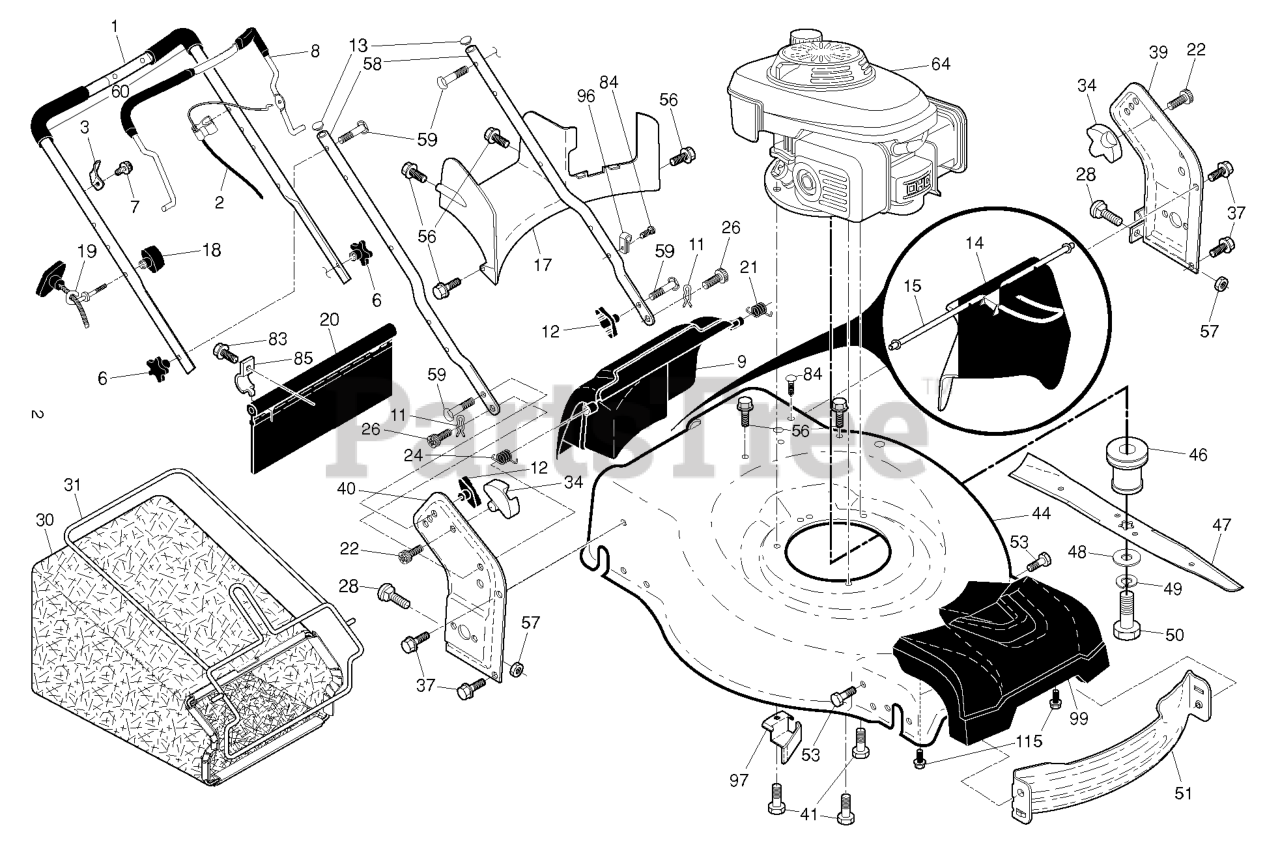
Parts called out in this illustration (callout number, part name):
1	HANDLE.UPPER.3.POS.BS.AW2.GREY
1	HANDLE.ASM.UPPER.W/GRIP
2	CABLE.MZR.50.SNAP-IN
3	BRACKET.UPSTOP.RT
6	KNOB.HANDLE.PLASTIC.STAR.BLACK
8	BAIL.OVER.MOLD.ERGO.MZR.ORANGE
9	DOOR.REAR.ASM.22+.HUSQ.FG/RGD
11	COTTER.HAIRPIN.DOOR/HANDLE.PIV
12	KNOB, DEFLECTOR
13	PLUG.PLASTIC.7/8".14-20.GAUGE
14	DEFLECTOR.CHUTE.22+REAR
15	HANDLE DEFLECTOR.22+REAR
17	BAFFLE.REAR.22+RGD.AWD.PLASTIC
18	T-KNOB.NEW ROPE GUIDE
19	GUIDE.ROPE.BLK.ZINC.CHROM
20	SKIRT.REAR.22+RGD.HIGH WHEEL
20	SKIRT.REAR.22PLUS.RGD.LW(2 2MC
21	SPRING.LH.BLACK
22	SCREW.PAN.HEAD.#10
24	SPRING.RH.GRAY
26	BOLT.CARRIAGE.LN.5/16-18X.5/8
26	SCREW,DOOR/HANDLE.PIVOT
28	BOLT
30	GBAG.A361029ER.HUSQ.GRY/SIL
31	FRAME.GBAG.22+.BLK
34	BRACKET.GRASSBAG.ATTACHING.BLK
37	BOLT.5/16HEX.WHS.HD
39	BRACKET.ASM.HANDLE.LT.22+.GREY
39	BRACKET.ASM.HNDL.LT.22+.GREY
39	BRACKET.HANDLE.LT.22+.W/DP.GRE
40	BRACKET.ASM.HANDLE.RT.22+.GREY
41	BOLT 3/8-16X1-1/8
44	HOUSING.22+RG.HD.WO.ORG.TRI.SB
44	HOUSING.22+.RWD.HD.WO/PORT.ORN
46	ADAPTER.BLADE.25MM.3MPH
47	BLADE.22+.PREMIUM/PREC.FGD/RGD
48	WASHER,HARDEN
49	LOCKWASHER
50	SCREW, HEX HD 3/8-24 X 1-3/8
51	BAFFLE.FRONT.22.PLUS
51	BAFFLE.FRONT.22+PLASTIC.(2 2)
53	BOLT.5/16HEX.WHS.HD
56	SCREW.HX.13X.750
57	NUT.FLANGE.5/16
58	HANDLE.LOWER.22+BT.2PC.GRY
59	BOLT, HANDLE 5/16-18X1.75
60	GRIP.HANDLE.FOAM.WIDE.(1 SIDE)
83	TAPPING SCREW
84	FASTENER.PUSH.O.250X0.783
85	BRACKET.SKIRT.22+.BZP
96	CLIP.CABLE.BLK
97	BRACKET.BELT.GUIDE.22+.BZP
99	COVER.ASM.FRONT.HUSQ.22+RGD
115	SCREW.HI-LO. 5/16 X 1.00
115	SCREW.HI-LO.5/16 X.75
